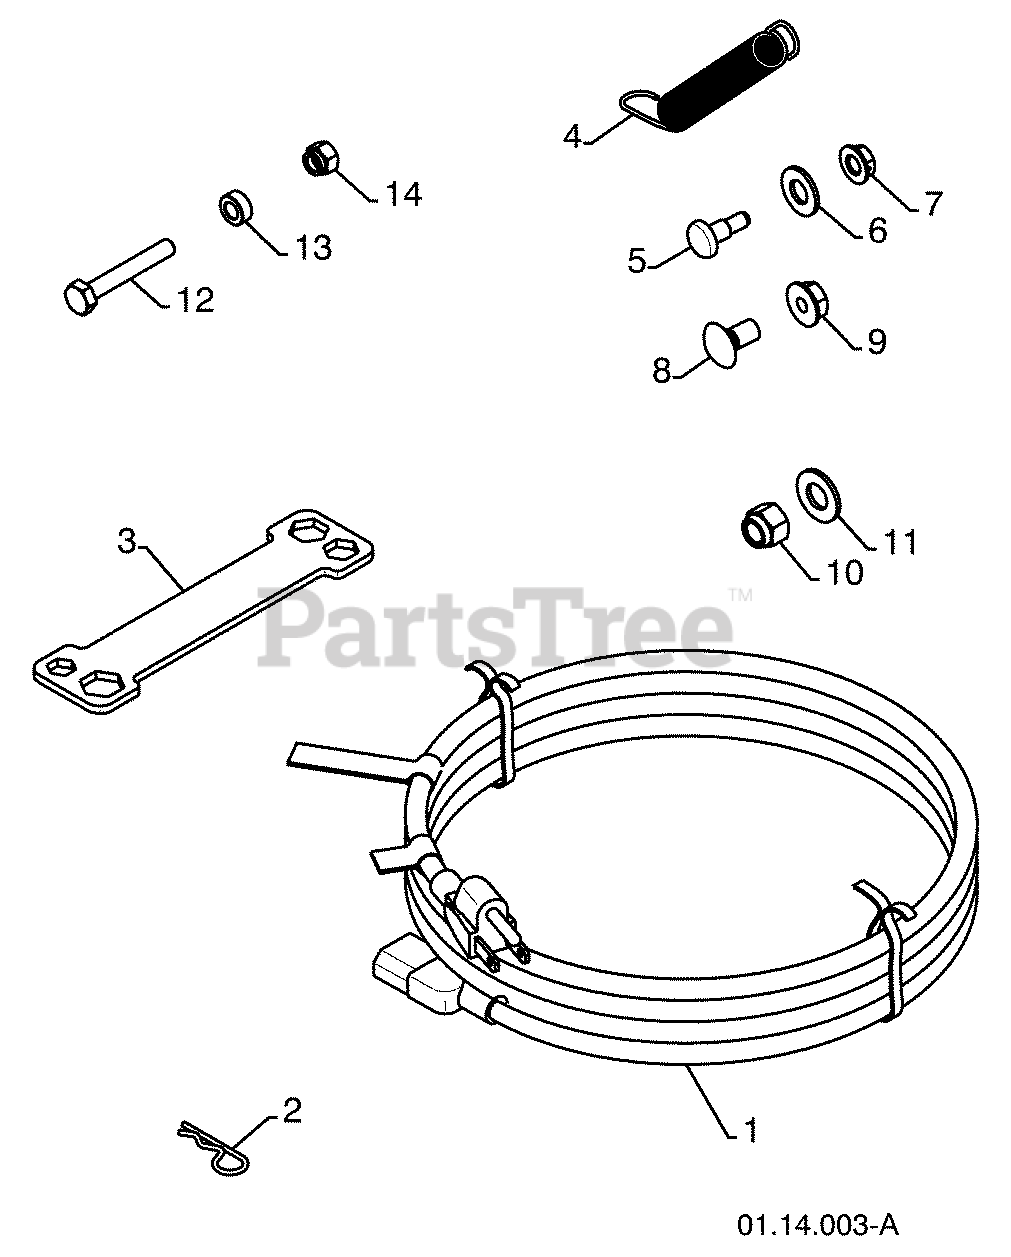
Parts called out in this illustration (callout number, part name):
1	POWER CORD
2	RETAINER PIN
3	WRENCH
4	REMOTE SPRING
5	SHOULDER BOLT 1/4-20
6	NYLON WASHER 1/4-20
7	LOCKNUT 1/4-20
8	CARRIAGE BOLT 5/16-18 X 5/8
9	LOCKNUT 5/16-18
10	LOCKNUT 3/8-16
11	WASHER 3/8
12	SHEAR BOLT 1/4-20 X 1-3/4
14	LOCKNUT 1/4-20
